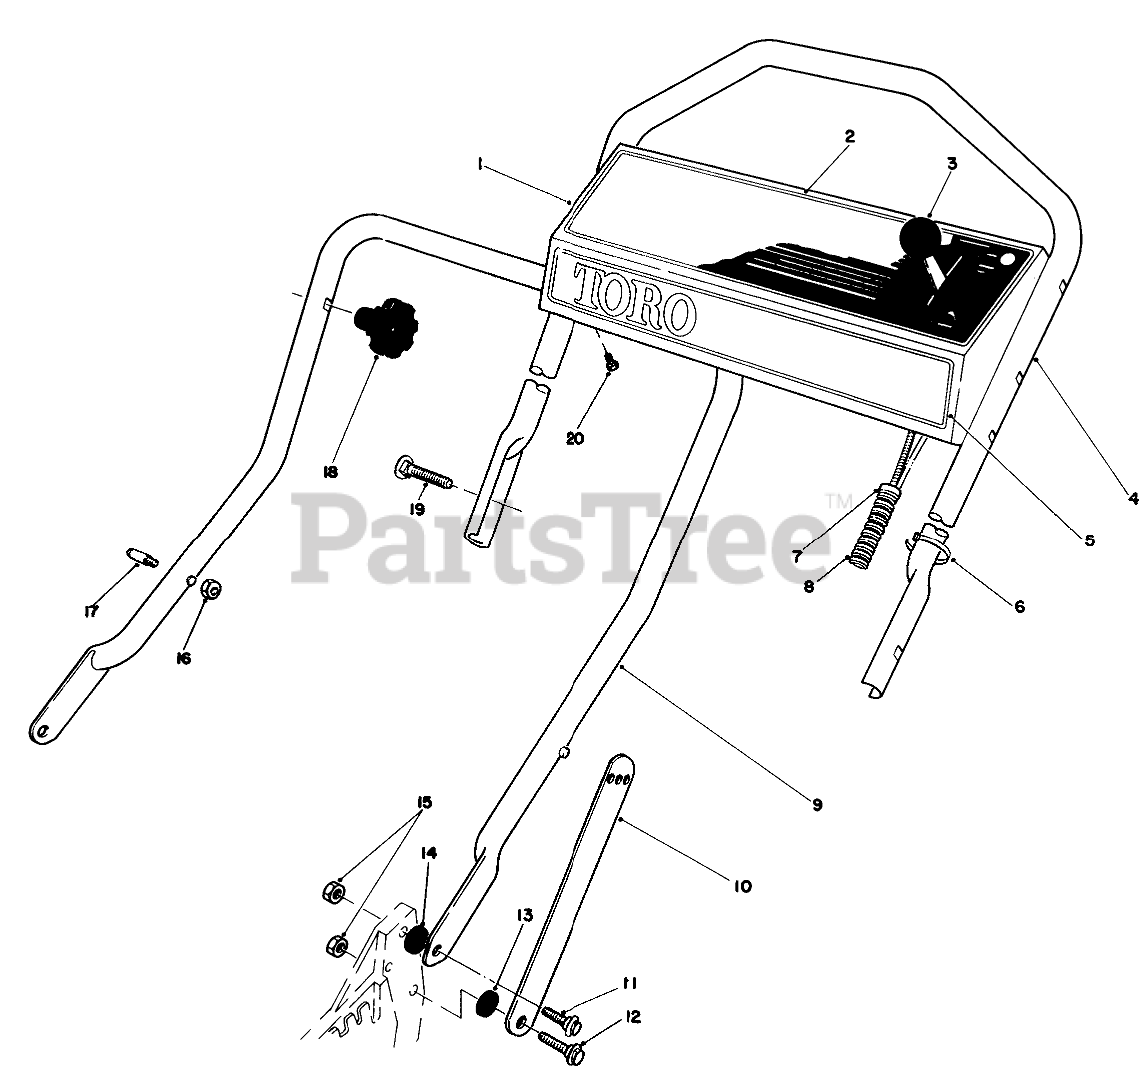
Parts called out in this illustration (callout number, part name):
1	Panel-Control (Incl. Ref. #2)
2	OBS INSTRUCTION DECAL
3	SERVICE TRACT. CONTROL
4	Handle-Upper
5	Decal-Toro
6	TIE-CABLE
7	FITTING-RING
8	CONTROL CABLE COVER
9	LOWER HANDLE ASM
10	Handle Latch
11	SCREW-SHOULDER
12	SCREW-SHOULDER
13	SPACER
14	SPACER
15	NUT-LOCK, NI
16	NUT-LOCK, NI
17	HANDLE PIN
19	5/16-18 X 2 HNDLE SCREW
20	SCREW-HWHTF
